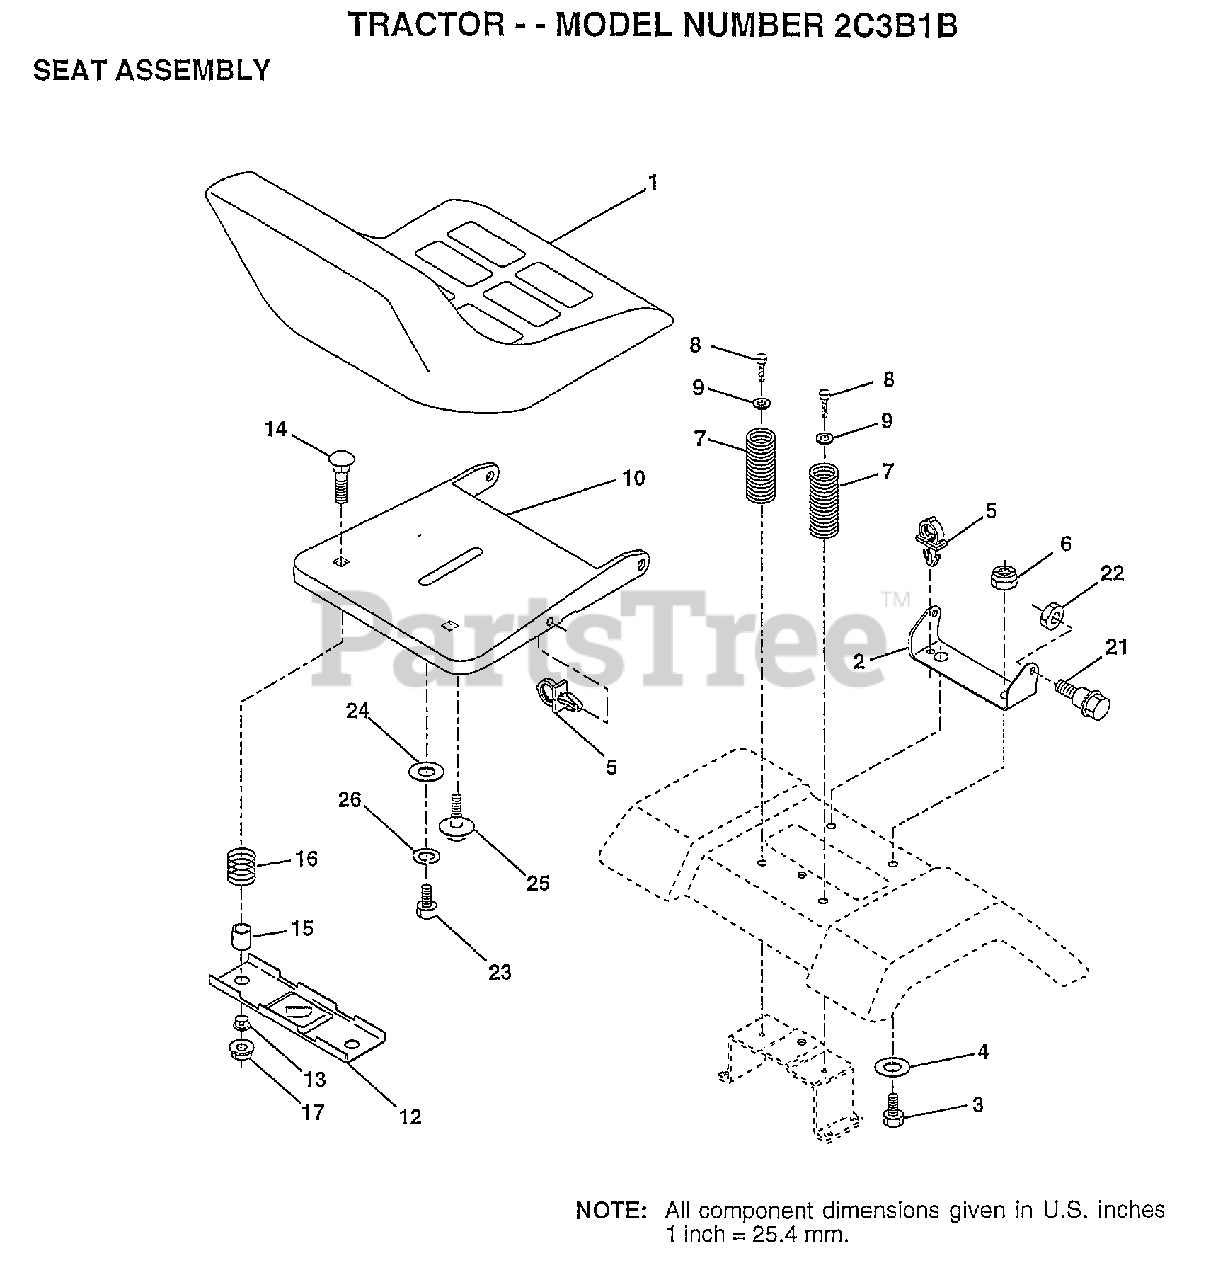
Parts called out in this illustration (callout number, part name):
2	BRACKET PVT SEAT
3	BOLT
4	WASHER PM
5	CLIP.PUSH-IN.HING
6	NUT
7	SPRING COMPRESSIO
8	SCREW GTV
9	WASHER
12	BRKT SWITCH
13	BUSHING
15	SPLIT SPACER
21	"BOLT,SHOULDER"
22	NUT
23	BOLT
24	WASHER
25	"BOLT,SHOULDER"
26	LOCKWASHER
